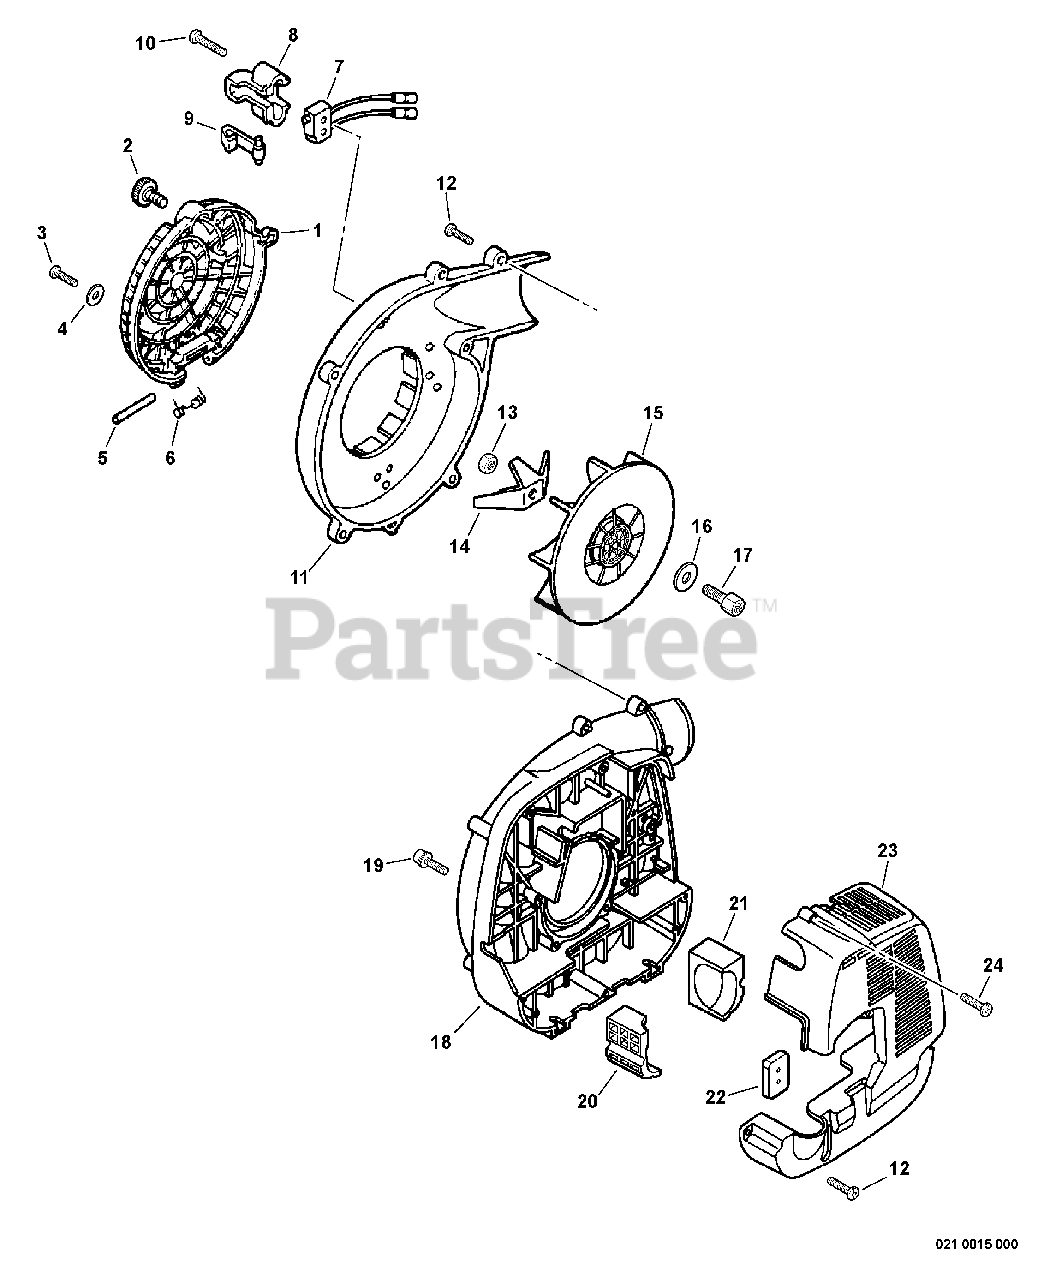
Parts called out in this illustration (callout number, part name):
1	COVER, INTAKE
2	THUMBSCREW
3	SCREW 5×14
4	WASHER 5.5×12×0.8
5	PIN, INTAKE COVER
6	SPRING, COIL
7	SWITCH, INTERLOCK
8	BRACKET, SWITCH
9	LEVER, SHUT OFF ACTUATOR
10	SCREW 4×22
11	COVER, FAN - LEFT
12	SCREW, TAPPING 5×20
14	SHREDDER
17	HUB, FAN
18	FAN CASE ASSY - INNER
19	SCREW 5×20
20	CUSHION
21	CUSHION
22	CUSHION
23	COVER, ENGINE
24	SCREW 5×20
